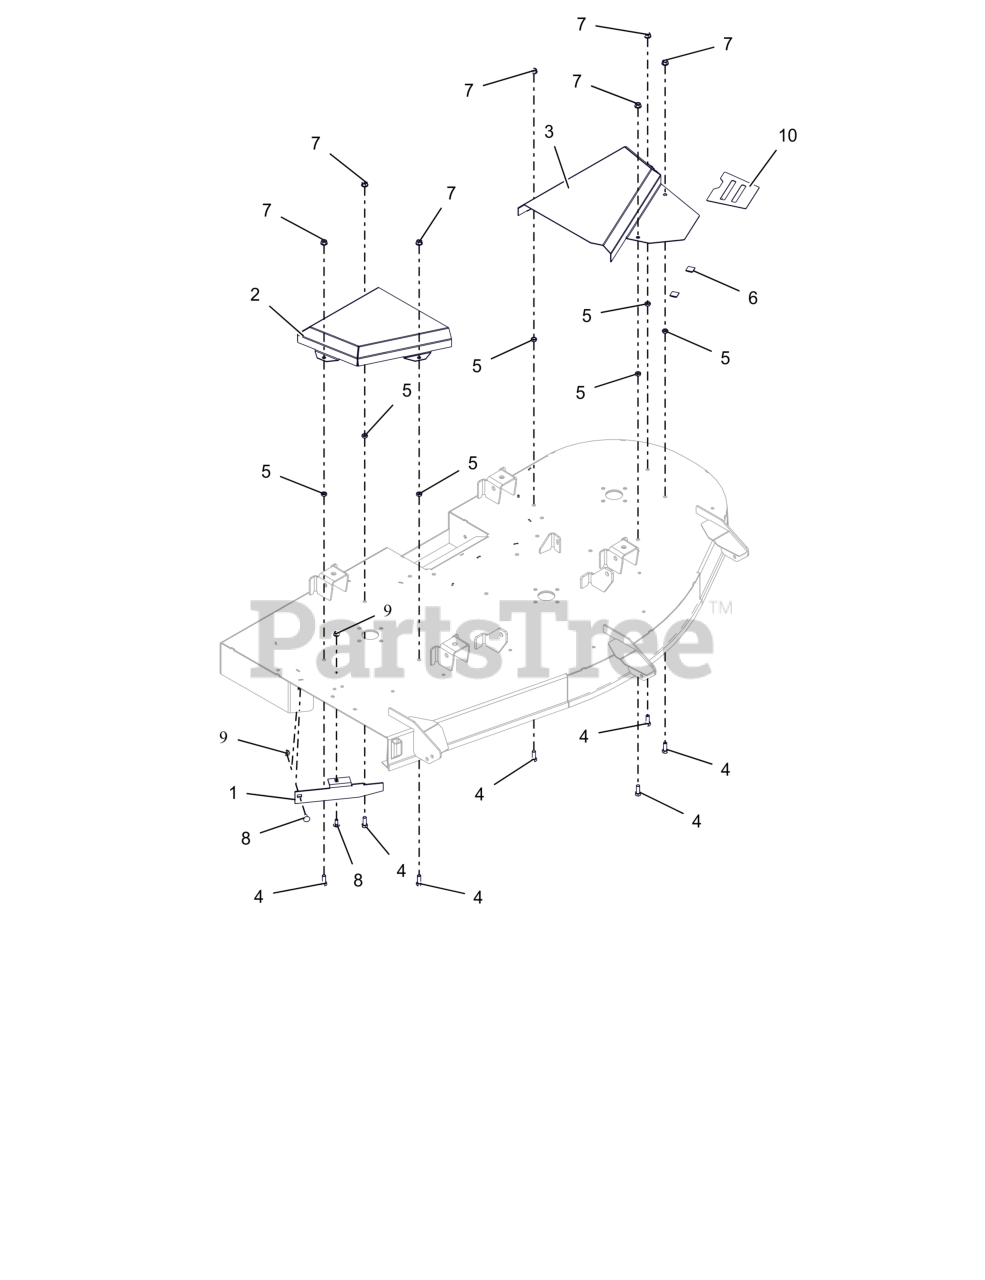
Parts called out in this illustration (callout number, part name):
1	BAFFLE, DISCHARGE 60"
2	COVER, BELT RH 60"
3	COVER, LH BELT 60
4	BLT,HEX .38-16X1.00 G5 ZCC
5	NUT-JAM .375-16 G2 ZCC
7	NUT-LK-CTR-FLG .375-16 GF ZCC
8	BLT,RHSN .31-18X.75 G5 ZCC
9	NUT-LK-TOP-FLG .312-18 GF ZCC
10	GRIP, TAPE 52-60 BELT COVER
